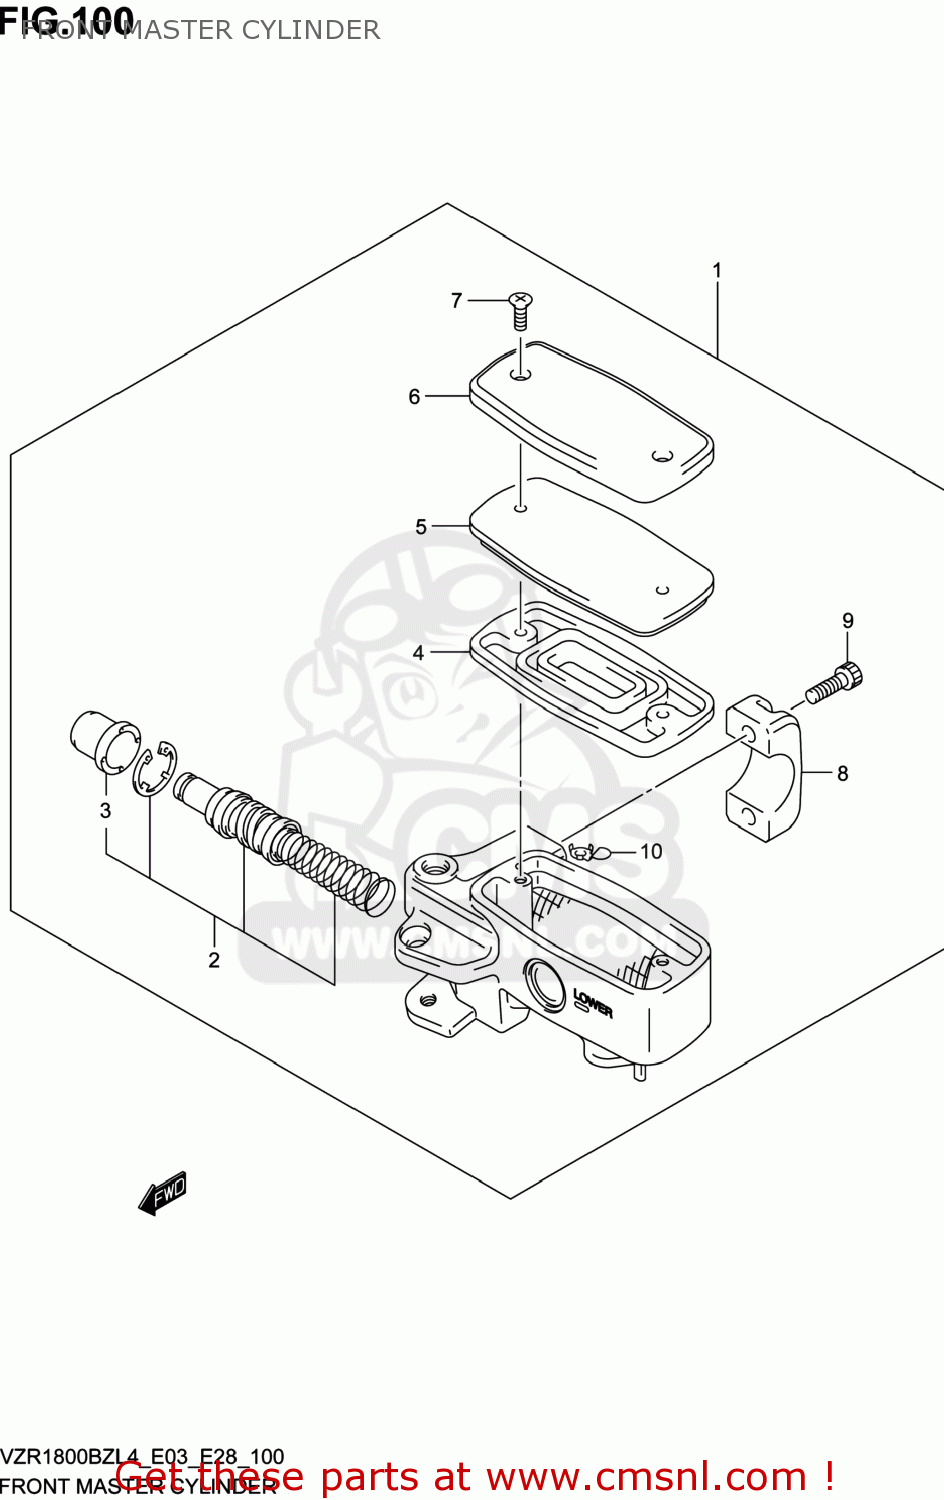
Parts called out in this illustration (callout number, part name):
1	CYLINDER ASSY,FRONT MASTER
2	PISTON/CUP SET
3	BOOT
4	DIAPHRAGM
5	PLATE,DIAPHRAGM
6	CAP
7	SCREW
8	HOLDER
9	BOLT
10	PROTECTOR
